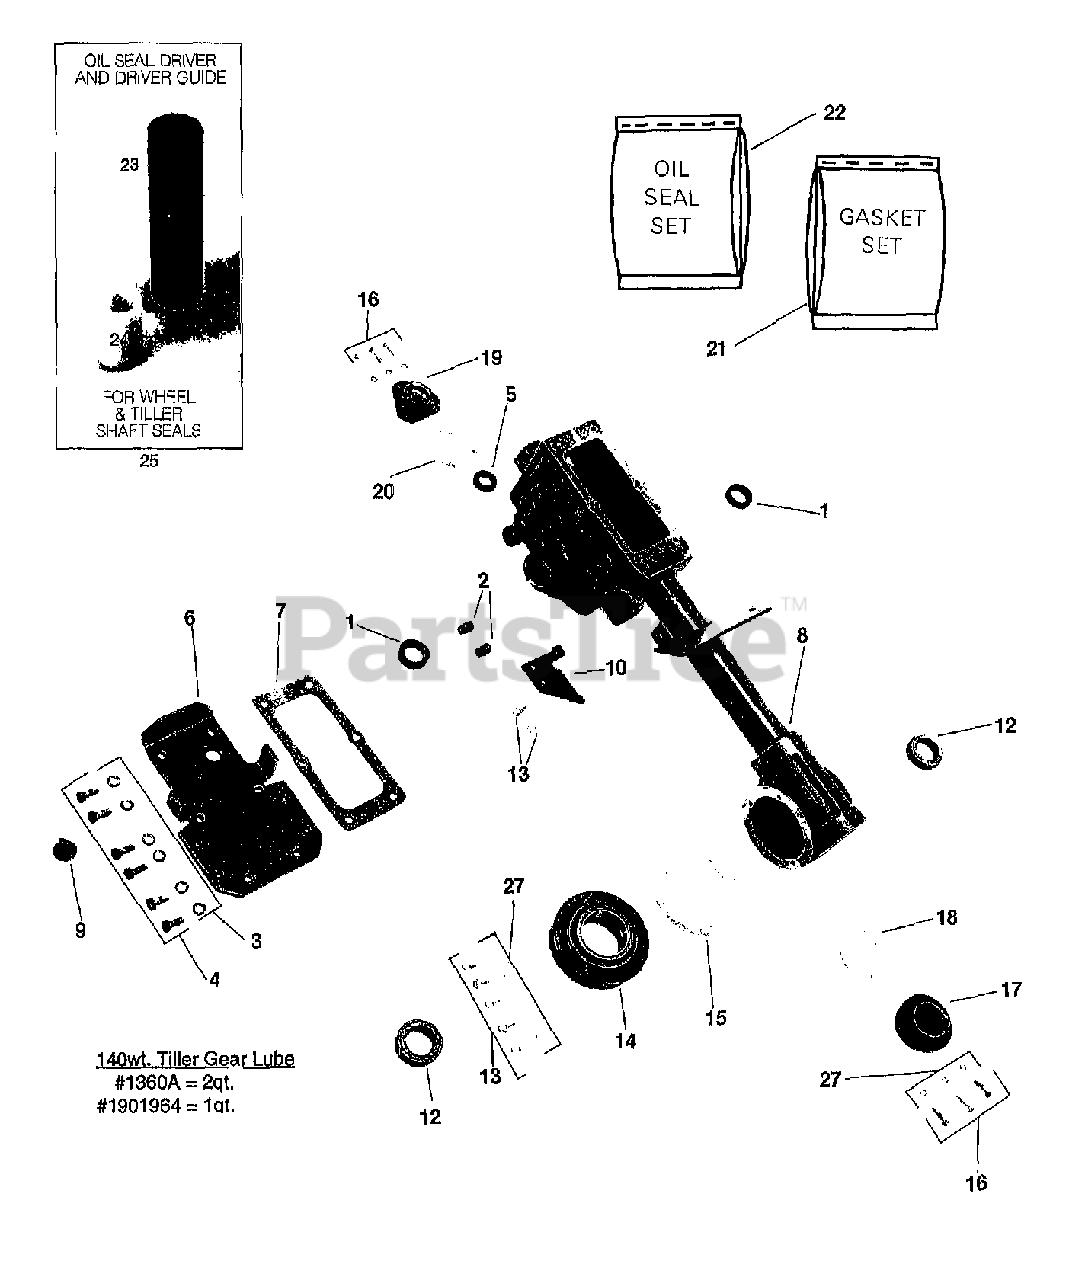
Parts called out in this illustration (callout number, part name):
1	OIL SEAL-double lip, wheel shaft, right and left sides
2	PLUG-pipe, 1/4", oil level hole and gear oil drain hole
3	LOCKWASHER-5/16", transmission top cover
4	BOLT- hex head, 5/16"-18 x 3/4",transmission top cover
5	OIL SEAL- input pinion shaft, front of transmission
6	COVER-top of transmission
7	GASKET-transmission top cover
8	TRANSMISSION CASE, REAR HOUSING & TUBE ASSEMBLY-
9	PLUG-for gear oil fill hole on transmission cover
10	PLATE-mounts on transmission housing
12	OIL SEAL-tiller shaft, left and right sides
13	BOLT-hex head, flanged self-locking, 1/4"-20 x 5/8"
14	COVER-tiller housing, left side,
15	GASKET-tiller housing cover, .010" thick (fits all covers)
16	BOLT-hex head, flanged self-locking. 1/4"-20 x 7/8"
17	CAP-rear bearing
18	GASKET-rear bearing cap, .010" thick
19	CAP-front bearing
20	GASKET-front bearing cap, .010" thick
21	GASKET SET-
22	OIL SEAL SET-
23	OIL SEAL DRIVER-
24	OIL SEAL DRIVER GUIDE-to install wheel shaft and tiller shaft oil seals (use with Part #4921-1)
25	OIL SEAL DRIVER & GUIDE SET-
27	WASHER-nylon, not reusable
